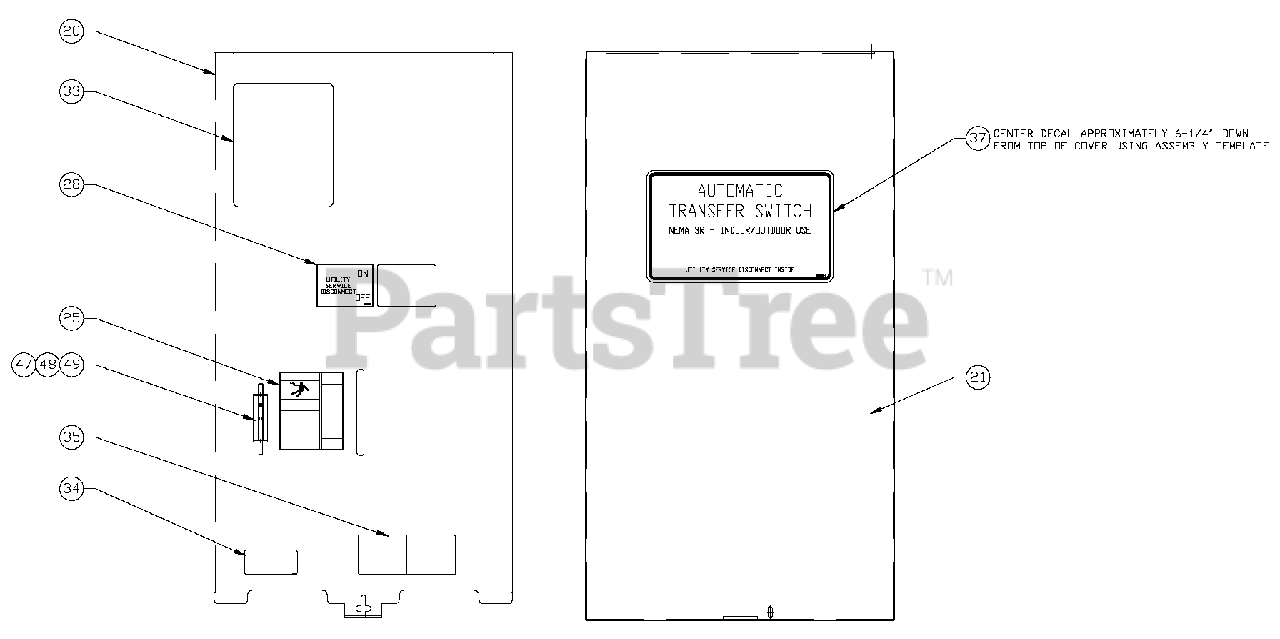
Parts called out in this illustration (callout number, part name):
20	COVER, INSIDE 200A DUAL BREAKER
21	COVER, TRANSFER SWITCH
25	DECAL, MANUAL OPERATING
28	DECAL, UTILITY DISCONNECT
33	DECAL, TEST SEQUENCE
34	DECAL LIVE CIRCUIT ENG/FRN/SPN
35	DECAL, TERMINAL SHOCK HZD BI
37	DECAL, FRNT CVR ATS 3R SER DIS
47	BRACKET, ARM EXTENDER
48	RIVET POP .156 X .362 AL
49	ARM EXTENDER PIN
